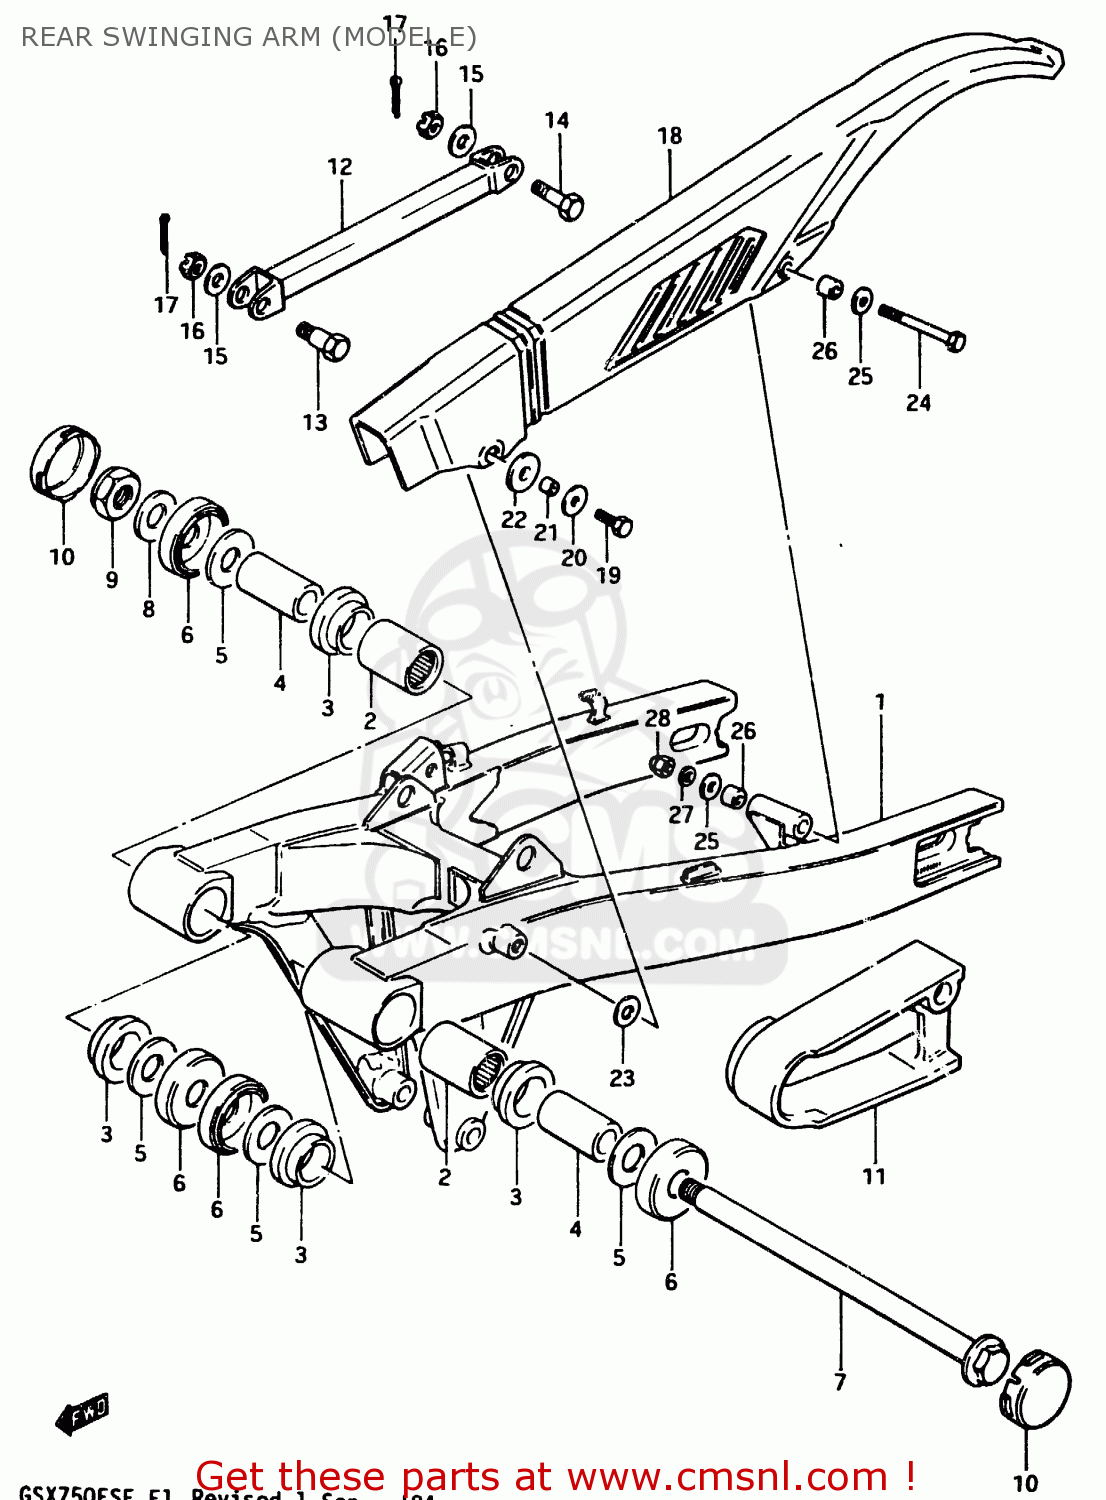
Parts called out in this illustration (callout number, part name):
1	SWINGING ARM SET
2	BEARING(25X33X30)
3	BUSHING
4	SPACER,RR SWGARM PIVOT
5	WASHER
6	COVER,RR SWINGINGARM PIVOT
7	SHAFT,REAR SWING ARM
8	WASHER
9	NUT
10	CAP,PIVOT
11	BUFFER,DEFENSE
12	TORQUE LINK,REAR
13	BOLT
14	BOLT(10X39)
15	WASHER
16	NUT
17	PIN 20X20
18	CASE,CHAIN
19	BOLT 6X16
20	WASHER (6.5X22X1.6)
21	SPACER
22	WASHER
23	WASHER (6.5X22X1.6)
24	BOLT 6X60
25	WASHER(6.5X18X1)
26	SPACER
27	WASHER,LOCK
28	NUT 6MM
